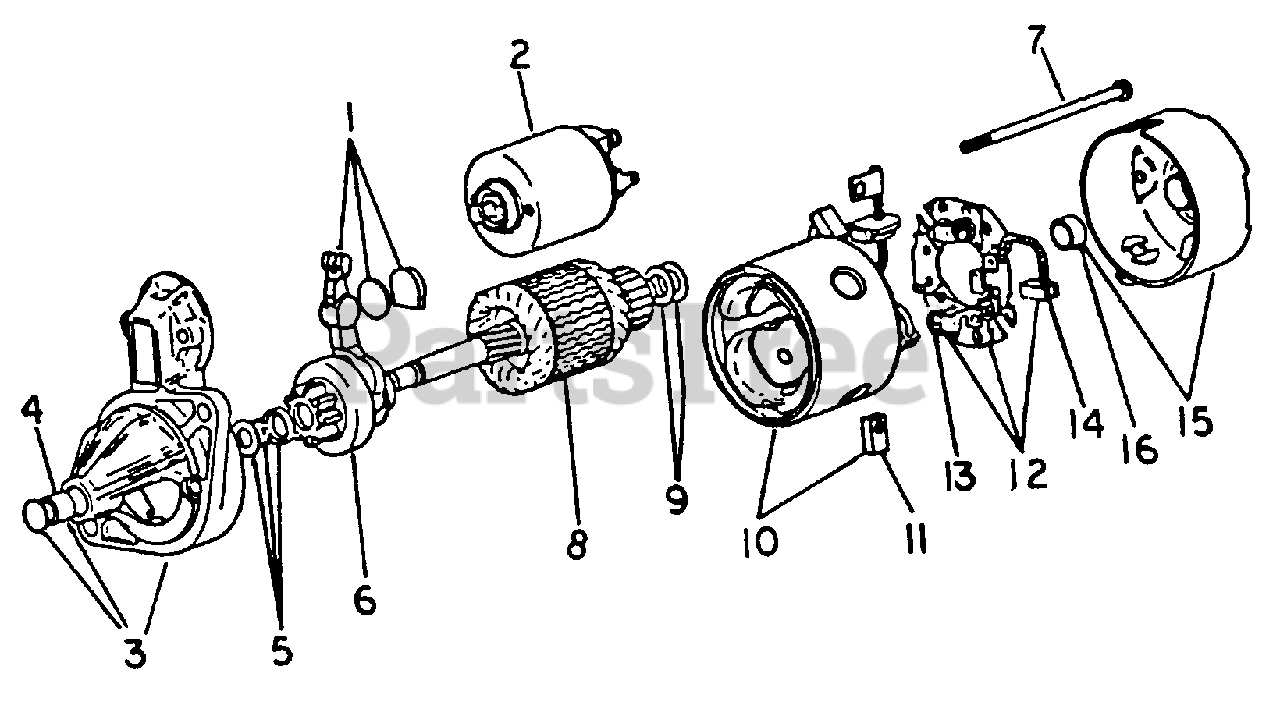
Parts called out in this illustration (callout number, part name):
2	Switch, Magnetic
3	Frame, Drive End
9	Washer, Adjusting
10	Yoke
12	Holder Assy, Brush
13	Spring, Brush
15	End Assy, Frame
